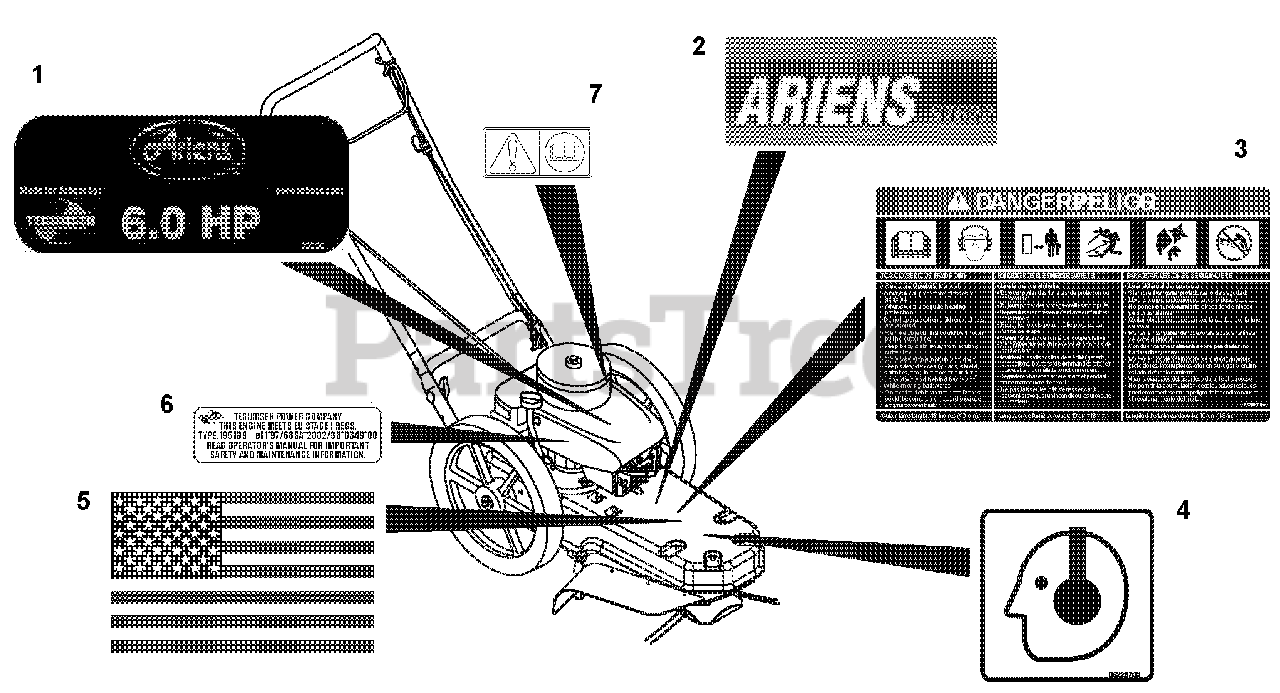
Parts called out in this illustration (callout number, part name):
1	DECAL - 6 HP ARIENS/TEC
2	DECAL - ARIENS ST 622
3	DECAL - DANGER-STRING TRIMMER
4	DECAL - EAR PROTECTION
5	DECAL, AMERICAN FLAG
6	DECAL, EU EMISSIONS
7	DECAL, EU ISO
